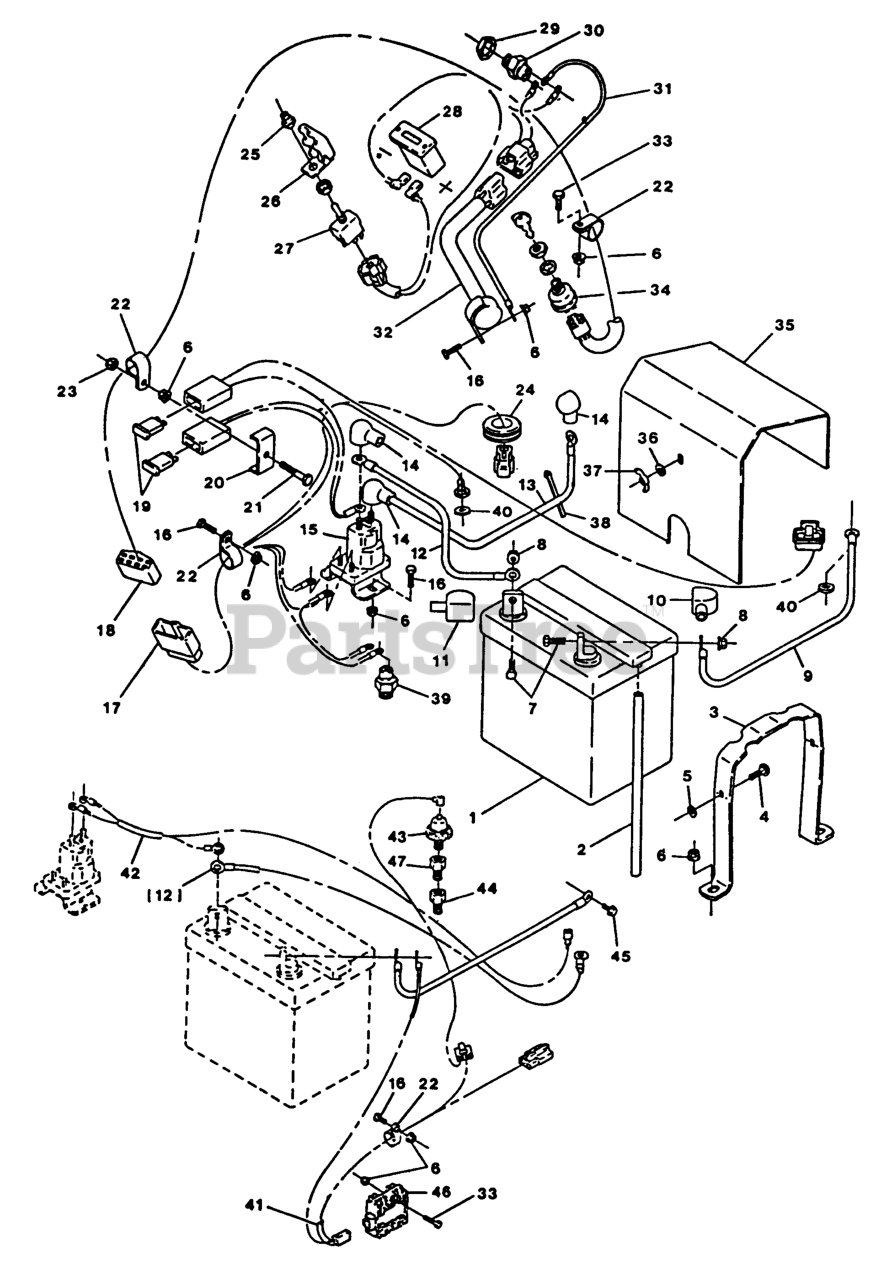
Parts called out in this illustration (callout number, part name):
1	Battery, 12v Manifold
4	BOLT-CARR
5	NUT-RETAINING
10	INSULATOR, BATTERY -
14	INSULATOR-SOLENOID
19	FUSE-BLADE TYPE, 20 AMP
20	CLIP-FUSE BLOCK PLTD
22	CLIP-LOOM
24	GROMMET
25	BOOT-SWITCH, TOGGLE
28	METER-HOUR
30	SWITCH,OPERATOR CNTRL
37	NUT-WING
38	TIE-CABLE
39	SWITCH-START, NEUTRAL
43	SWITCH-OIL PRESSURE
45	M8 X 1.25 X 16 Mm Hh Capscrew
